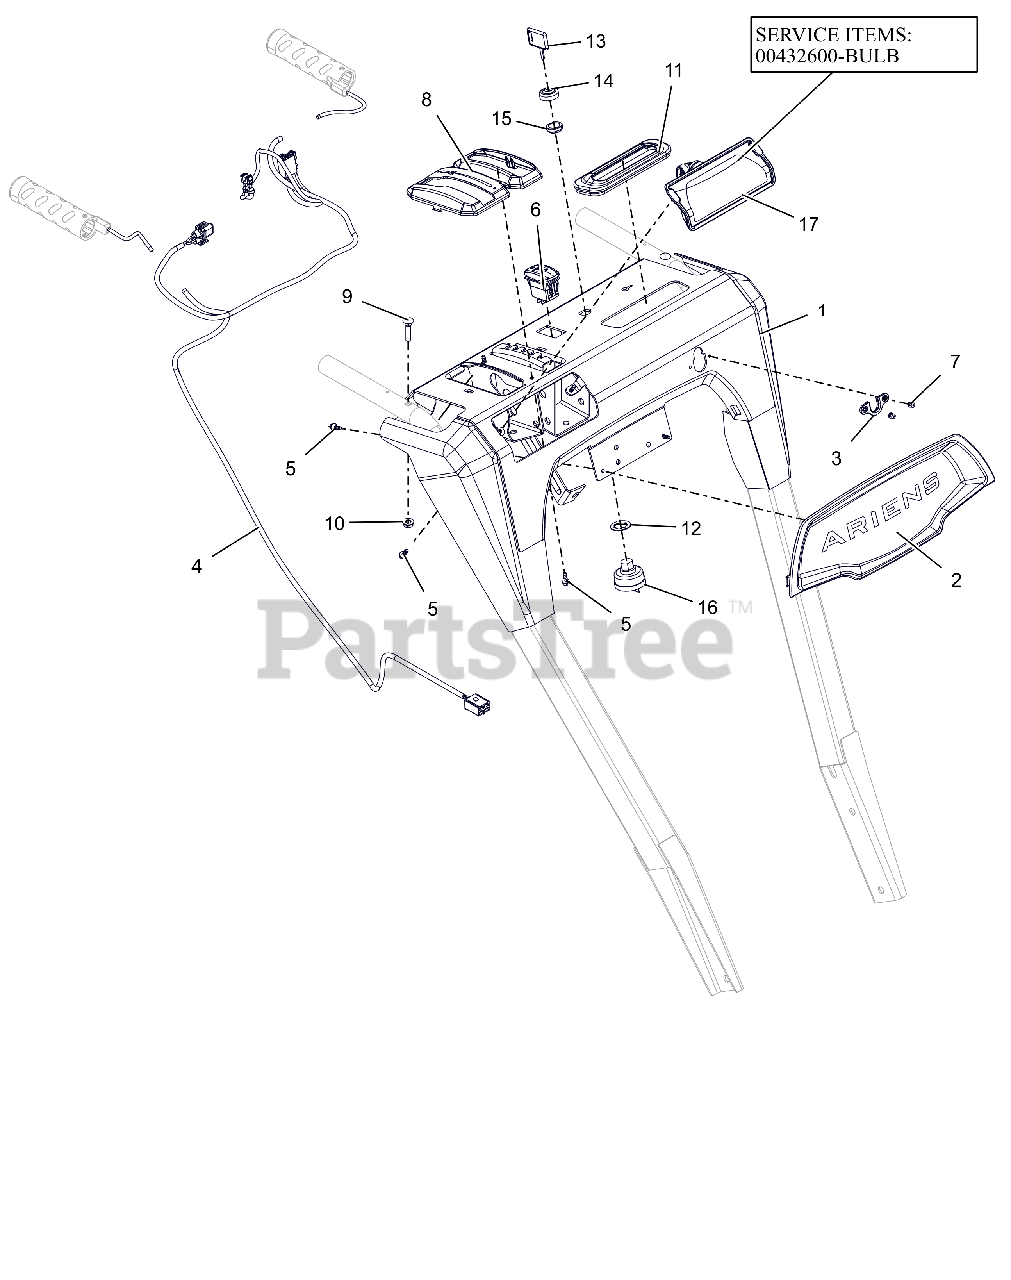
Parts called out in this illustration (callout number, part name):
1	PANEL, DASH-HYDRO 12V W/DECAL
2	BEZEL, DASH - ARIENS LG DASH
3	GROMMET, CABLE, QUICK TURN 2
4	HARNESS,ELEC - HANDLEBAR 12V
5	SCR-TAP #10X.50 BOSS INDHXHD
6	SWITCH,ROCKER SPST-ON/OFF
7	RVT-POP #43 .125X.313 STL ZINC
8	BEZEL, SHIFT - HYDRO SNOW
9	BLT-RDHDXLSQNK.25-20X1.25 G5ZC
10	@NUT-LK-CTR-FLG .25-20 YWZC
11	GROMMET, BOOT, QUICK TURN
12	WSHR-LK-INT .625X.045 YWZC
13	KEY -W/CAP
14	CAP - IGNITION SWITCH
15	NUT-PANEL .625-32 GRECO
16	IGNITION SWITCH ASSEMBLY
17	HEADLIGHT ASY, HALO 20W 2SHOT
17	BULB, LIGHT-HALOGEN 20W
